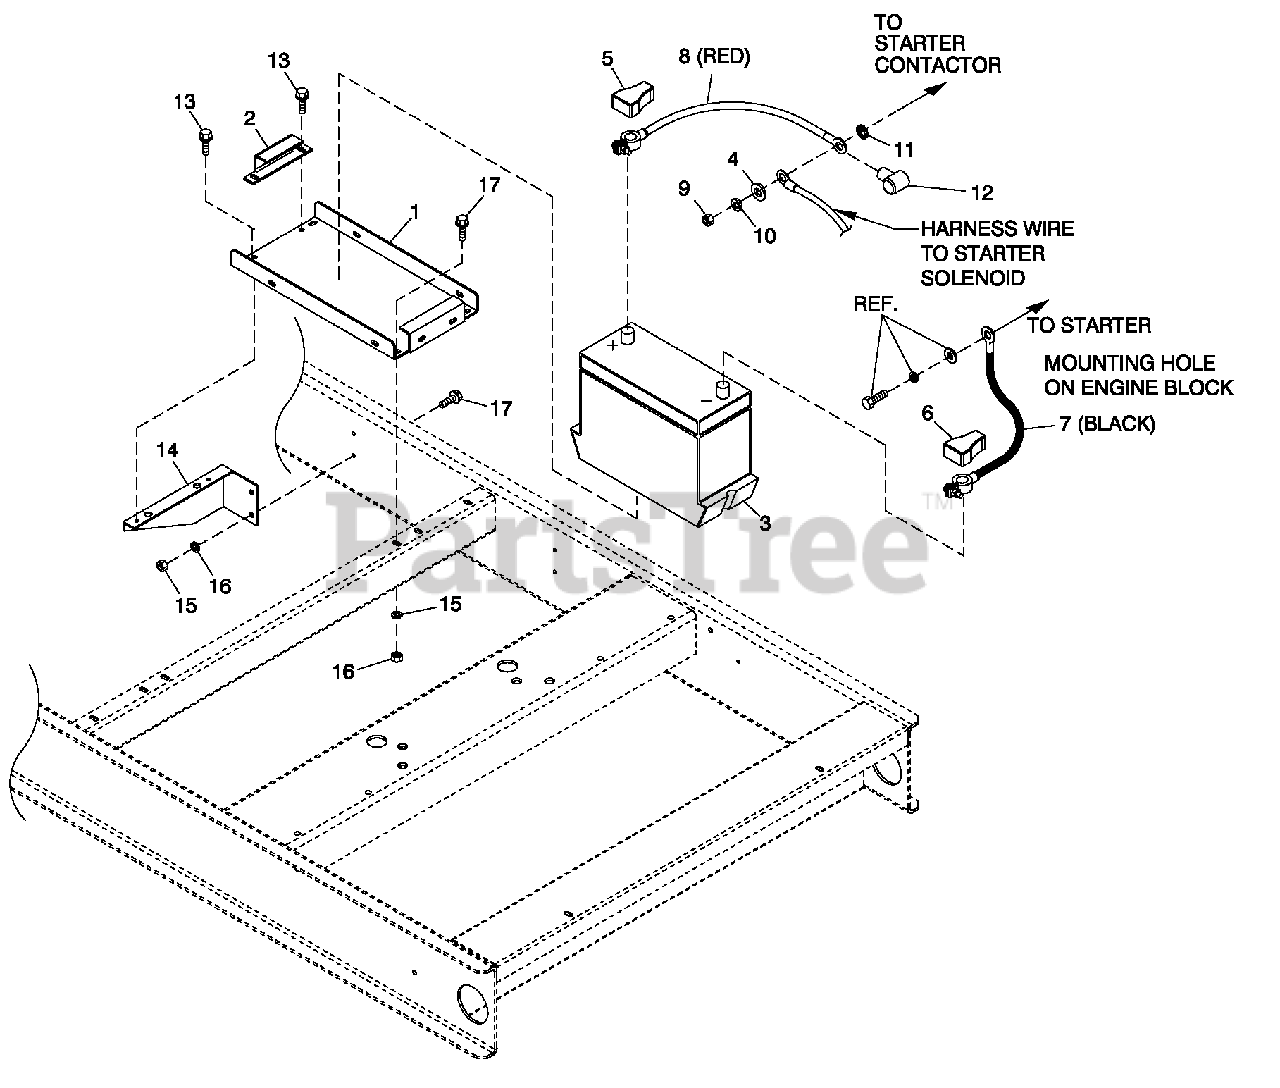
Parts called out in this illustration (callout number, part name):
1	TRAY BATTERY 27F
2	STRAP BATTERY RETAINMENT 27F
3	BATTERY 12VDC 90-AH 27F
4	WASHER FLAT 3/8-M10 ZINC
5	BATTERY POST COVER RED +
6	BATTERY POST COVER BLK -
7	CABLE BATTERY BLK #1 X 18.00
8	CABLE BATTERY RED #1 X 28.00
9	NUT HEX M8-1.25 G8 YEL CHR
10	WASHER LOCK M8-5/16
11	WASHER SHAKEPROOF EXT 5/16 STL
12	BOOT BATTERY CABLE
13	SCREW THF M6-1 X 16 N WA Z/JS
14	SUPPORT BATTERY TRAY
15	WASHER LOCK M6-1/4
16	NUT HEX M6 X 1.0 G8 YEL CHR
17	SCREW HHC M6-1.0 X 20 G8.8
